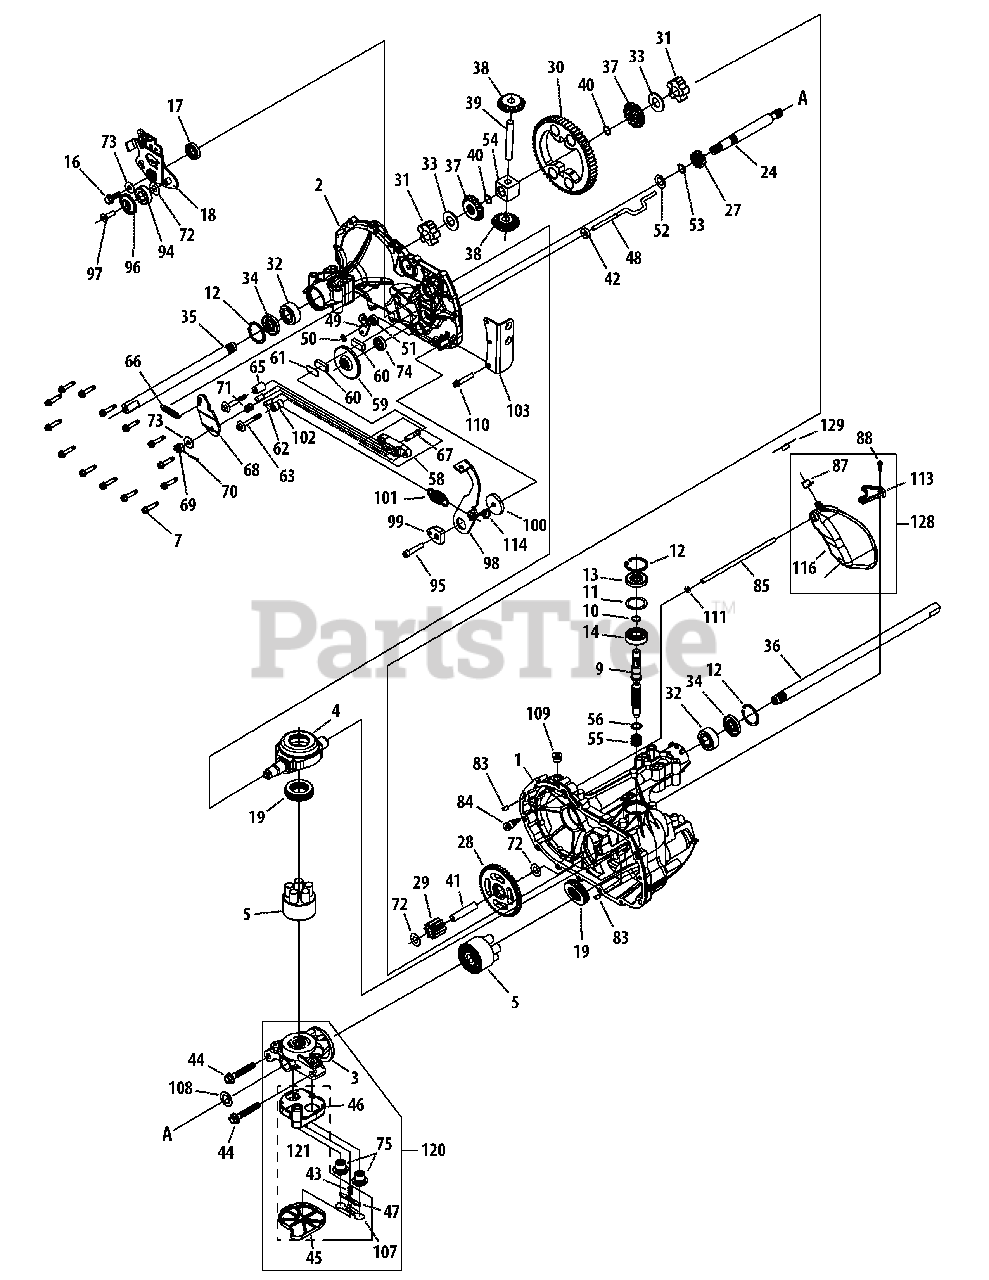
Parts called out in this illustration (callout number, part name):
1	Main Housing Assembly
1	Main Housing, Machined
1	Bushing ,865 x 985 x .790
2	Main Housing Assembly
2	Main Housing, Machined
2	Bushing ,865 x 985 x .790
2	Bushing 624 x 719 x . 562
3	Center Section Assembly
3	Center Section Machined
3	Bushing. 707 x . 788 x . 591
4	Swashplate, Trunnion Machined
5	Block - Assembly
5	Block - Cylinder
5	Piston
5	Spring, Compression
5	Washer - Thrust
7	Hex Flange Screw 1/4-20 x-1,25
9	Shaft, Input
10	Ring - Retaining
12	Ring - Retaining
13	SeaL Lip .67 x 1.58 x .276
14	Ball Bearing 17mm Id x 40mm Od
16	Bolt. Flange 5/16-24 x .94 (Patch)
17	Lip Seal 18 x 32 x 7
18	Arm Control
19	Bearing 30x52 x 13 Thrust
24	Shaft Motor
27	Gear - Pinnion 12t
28	10t/49t Gear
29	Gear Jot Jackshaft
30	60t Bull Gear
31	Sleeve Bearing . 75 x 1.750 x .625
32	Sleeve Bearing .75 x 1.575 x ,625
33	Washer 3/4 Id x 1-1/2 Od x .13 Thk
34	Lip Seal Axle Seal
35	Shaft Axle . 75 x 11. 39 ( Dd R. H, )
36	Shaft Axle .75 x 17. 99 ( Dd, L, H.)
37	Miter Gear (Splined)
38	Miter Gear 15t (0 .5 Id)
40	Ring, Spiral Retaining
41	Pin, Jackshaft
42	Magnet, Ring
43	Spring, Bypass
44	Hydro Mtg Screw 3/8-24 x 2.5
45	Bottom, Filter
46	Base Filter W/ Poppet
47	Actuator Bypass
48	Rod Bypass Actuator
49	Arm, Bypass
50	Retaining Ring 0.250 External
51	Seal, Lip . 741 x .250 x .250 Tc
52	Flat Washer 5/8 Id x 1.0 Od x . 05
53	Retaining Ring
54	Bearing, Center Block
55	Spring - Helical Compression
58	Kit, Brake Yoke
58	Brake Yoke
58	Sq. Hd, Bolt 5/16-24 Ribbed
59	Rotor, Brake
60	Brake Puck
61	Puck Plate
62	Brake Actuating Pin
63	Hex Screw 1/4-20 x 2 w/ Patch
66	Kit, Spring
67	So. Hd, Bolt 5/16-24- Ribbed
68	Arm, Brake
69	Slotted Hex Nut 5/16-24
70	Cotter Pin 3/32 x 3/4
71	Comp. Spring Brake Anti-Drag
72	Washer, Ht .5 I. D. x 1 OD, x .032
73	Flat Washer, 11/32 ID x 7/8 OD
74	Kit, Seal
74	Oil, Seal 625 x Lo x .25
74	Ring, Ret-Star Washer
74	Bulletin, Shaft Seal
75	Check Plug Assem, .027 Washer
83	Pin, Standard Headless
84	Fitting, 5/16 Sae 5/32 Tube
85	Hose, Expansion Tank
87	Cap,. Vent
88	Bolt, Self Tapping 10-32 x 112
94	Ball Bearing .62 Id x 1,38 x 44
95	Cap Screw, 5/16-24 x 1-112
96	Spacer, Locating
97	Screw, Sfhcs
98	Arm, Return
99	Puck, Adjusting
100	Washer, .32 OD x 1.6 ID x .24
101	Spring, Extension
102	Spacer, .56 x .26 x .87
103	Bracket, Torque
107	Deflector
108	Washer, Motor Shaft .71 Id 1.15 Od
110	Torx Head Screw, 5/16-18
111	O-Ring, .07 x .301 ID
113	Bracket, Support Expansion Tank
114	Spring Guide
116	Silicon Sponge
120	Center Section - Bypass Assm
120	Center Section Machined
120	Base Filter w/ Poppet
120	Check Plug Assembly
120	Spring Bypass
120	Actuator Bypass
120	Deflector
120	Bottom, Filter
120	Bushing, .707 x .788 x .591
121	Filter Assembly
121	Bottom Filter
121	Base Filter w/ Poppet
121	Spring Bypass
121	Actuator Bypass
121	Deflector
128	Kit, Expansion Tank
128	Tank, Expansion
128	Cap, Vent
128	Bolt, Self Tapping 10-32 x 1/2
128	Bracket, Support Expansion Tank
128	Silicon-Sponge 112 x 1/2 x 3/16
129	Cap, Expansion Tank Shipping
